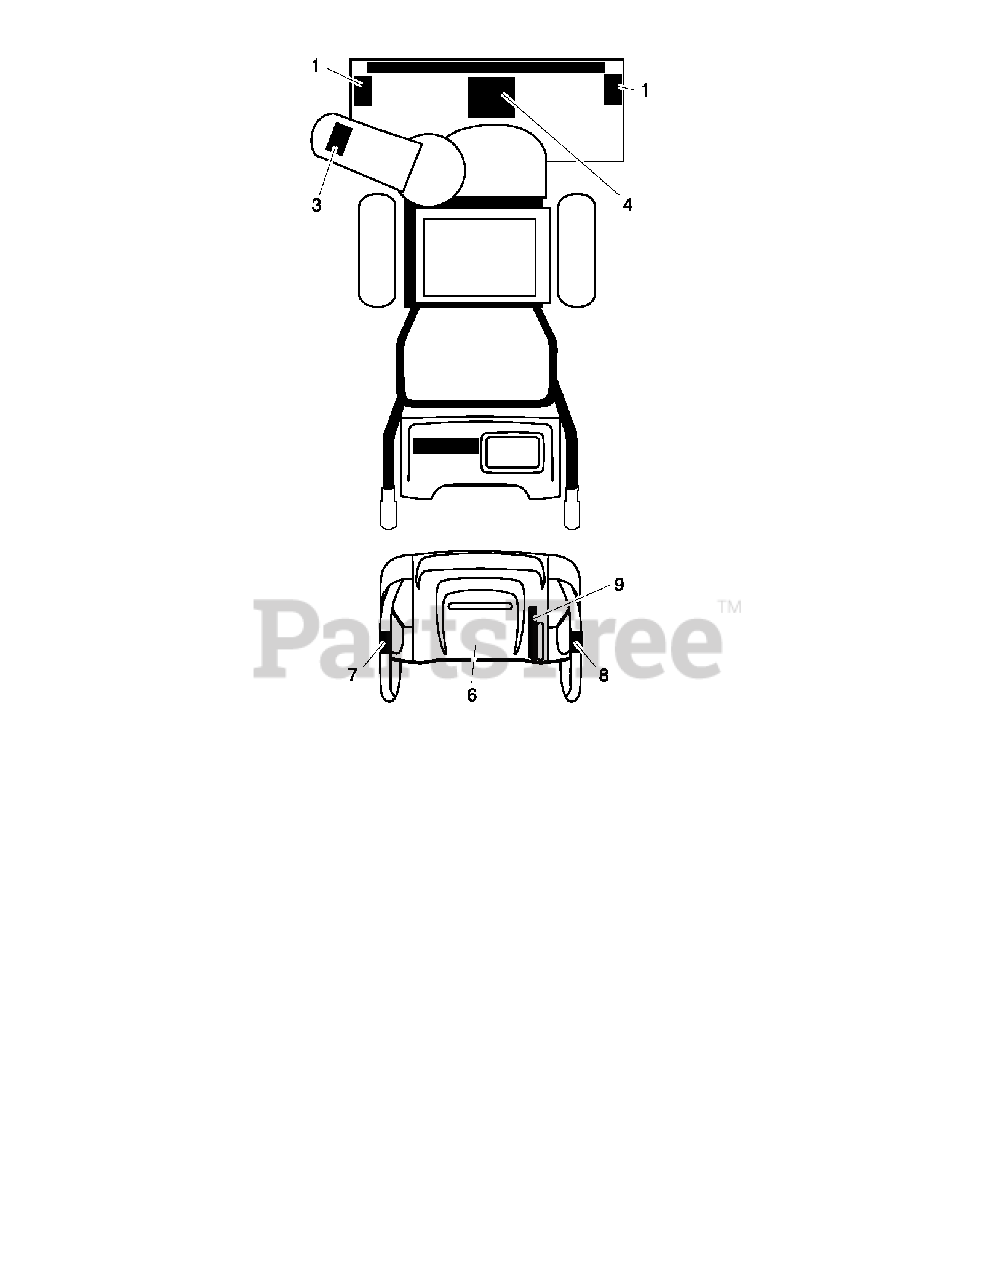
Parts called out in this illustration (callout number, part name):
1	DECAL.AUGER.SAFETY.
3	DECAL.CHUTE.SAFETY.
4	DECAL.AUGER."
6	DECAL.CONSOLE.INSTRUCTION
